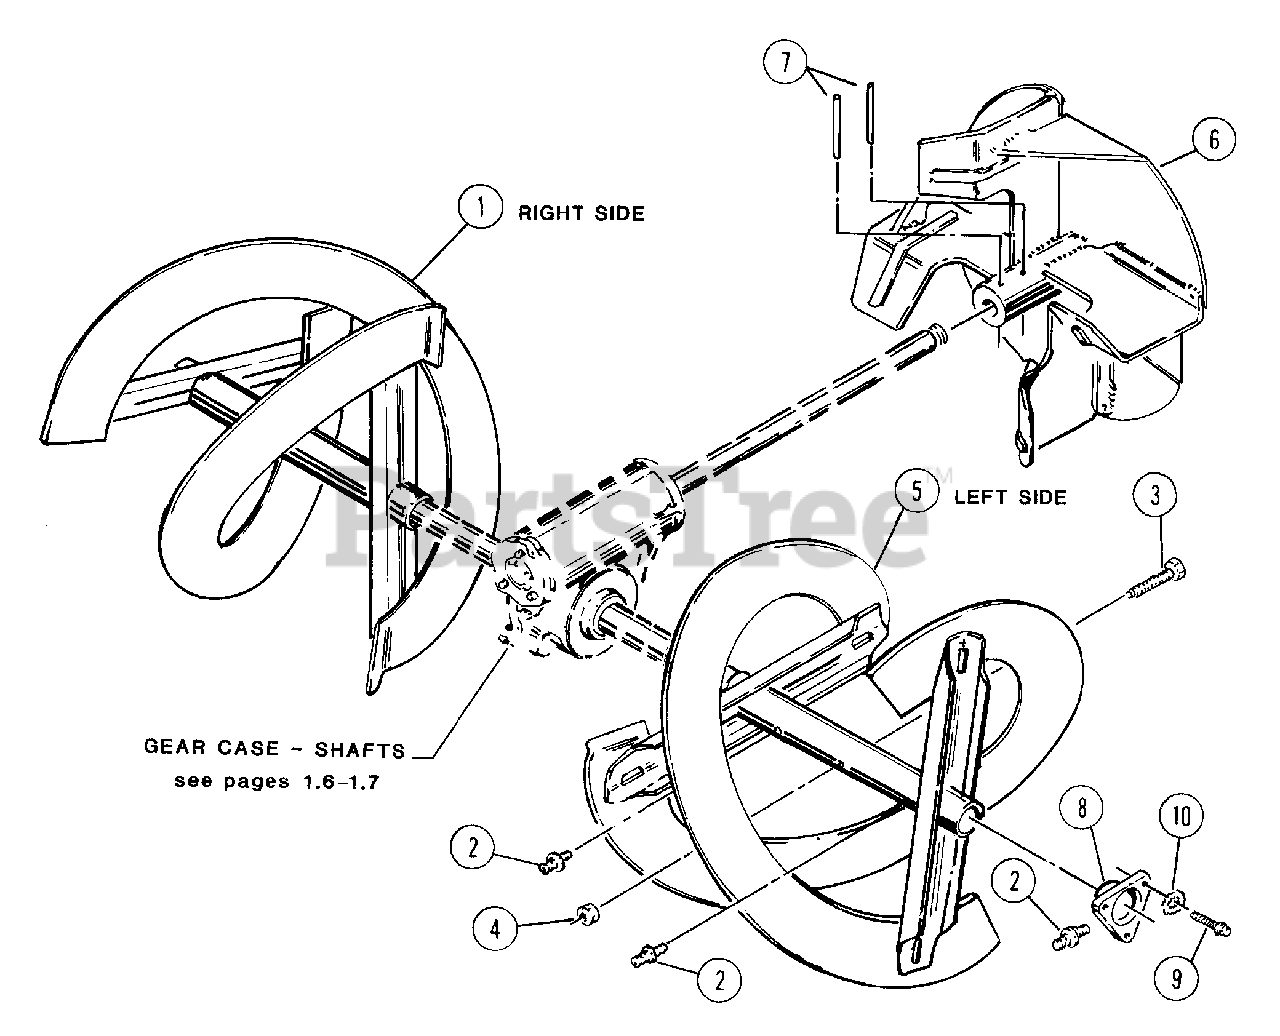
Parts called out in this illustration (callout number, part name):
1	AUGER, Right-23" Units Serial #03 Prefix only
1	AUGER, Right-23" Units-Serial #23 Prefix
1	AUGER, Right-26" Units-Serial #03 Prefix only
1	AUGER, Right-30" Units
2	FITTING, Grease (Straight Press Fit .187" Hole, .25" Deep)
3	BOLT, 5/16-18 x 1-7/8" Shear
4	NUT, 5/16-18 Hex Flange Lock
5	AUGER, Left-23" Units-Serial #03 Prefix only
5	AUGER, Left-23" Units-Serial #23 Prefix
5	AUGER, Left-26" Units-Serial #03 Prefix only
5	AUGER, Left-26" Units-Serial #23 Prefix
5	AUGER, Left-30" Units
6	IMPELLER (Fan)
7	PIN, 1/4 x 1-1/2" Roll
8	BEARING & FITTING ASSY. (.72" Wide) 26" & 30" Models
8	BEARING & FITTING ASSY. (1.22" Wide) 23" Models
9	SCREW, 5/16-18 x 3/4" Hex Washer Self-Tap
10	WASHER, 5/16 Internal Tooth Lock
11	LUBE FITTING, Straight (press-fit for .187 dia. Hole)
